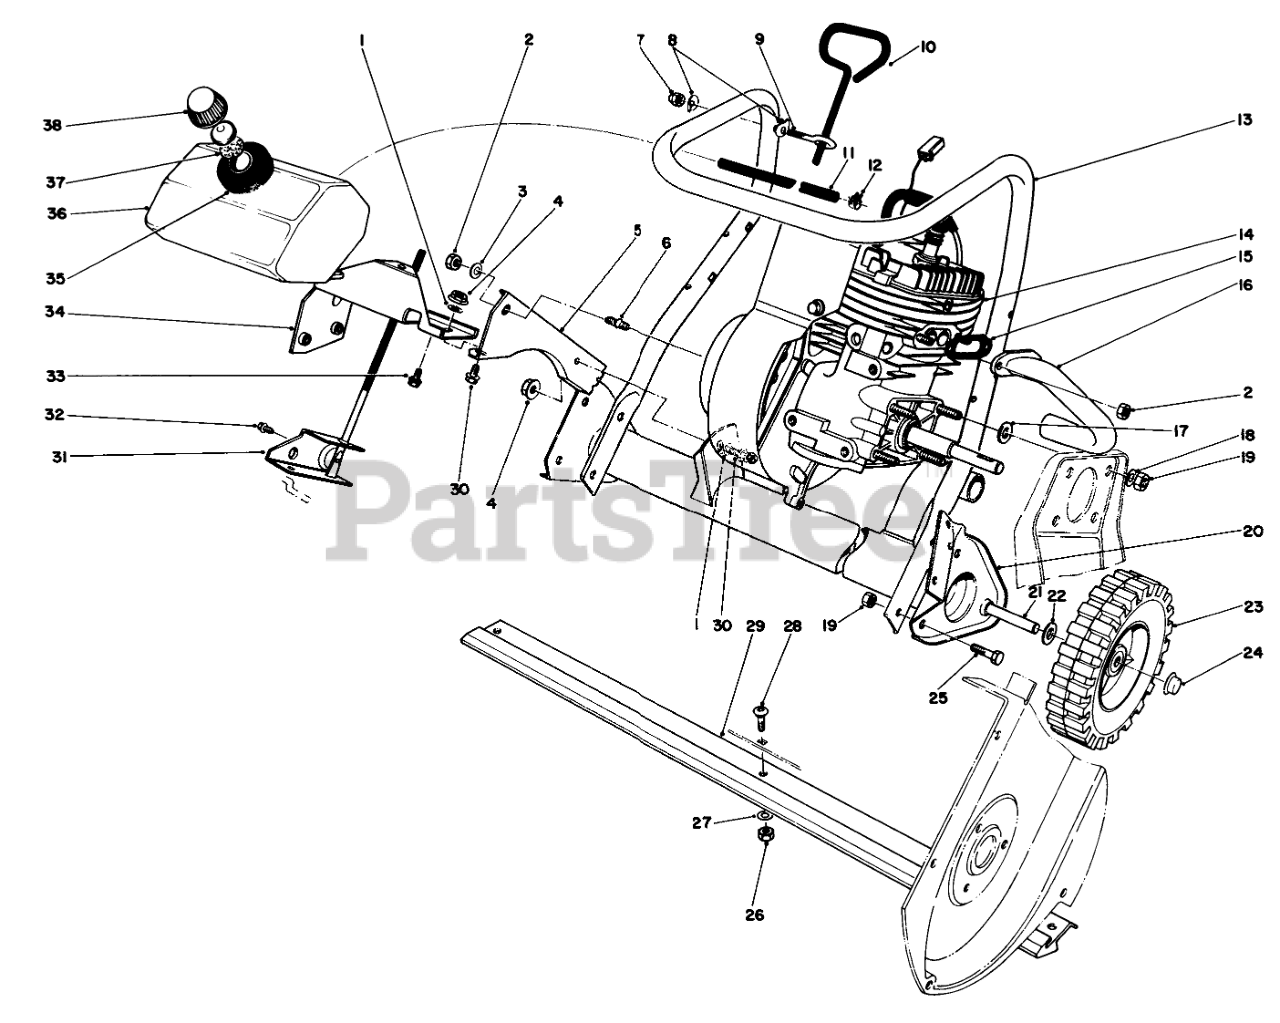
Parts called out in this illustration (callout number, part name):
1	WASHER-LOCK
2	NUT-LOCK, CONE
3	GRILLE HINGE SPACER
5	ENGINE SUPPORT
7	NUT-CAP
8	WASHER
9	EYEBOLT
10	ADJ ROD ASM
11	GasLine
12	Clamp
13	HANDLE-LOWER
15	EXHAUST GASKET
16	EXHAUST PIPE
17	WASHER-FLAT
18	WASHER-PLAIN
19	NUT-LOCK, NI
20	MUFFLER ASSEMBLY
22	WASHER-FLAT
23	WHEEL
24	RETAINER-PUSH ON
25	SCREW-HH
26	NUT-LOCK, NI
27	WASHER-FLAT
28	SCREW-PPH
29	SCRAPER
30	5/16-18X.62 WHIZLOK SCR
31	VANE ADJ BRKT
32	SCREW-TAPTITE
33	SCREW-HWH
34	Support-Gas Tank
35	FOAM PAD
36	GAS TANK
37	GAS CAP GASKET
38	Gas Cap (Incl. Ref. #36)
